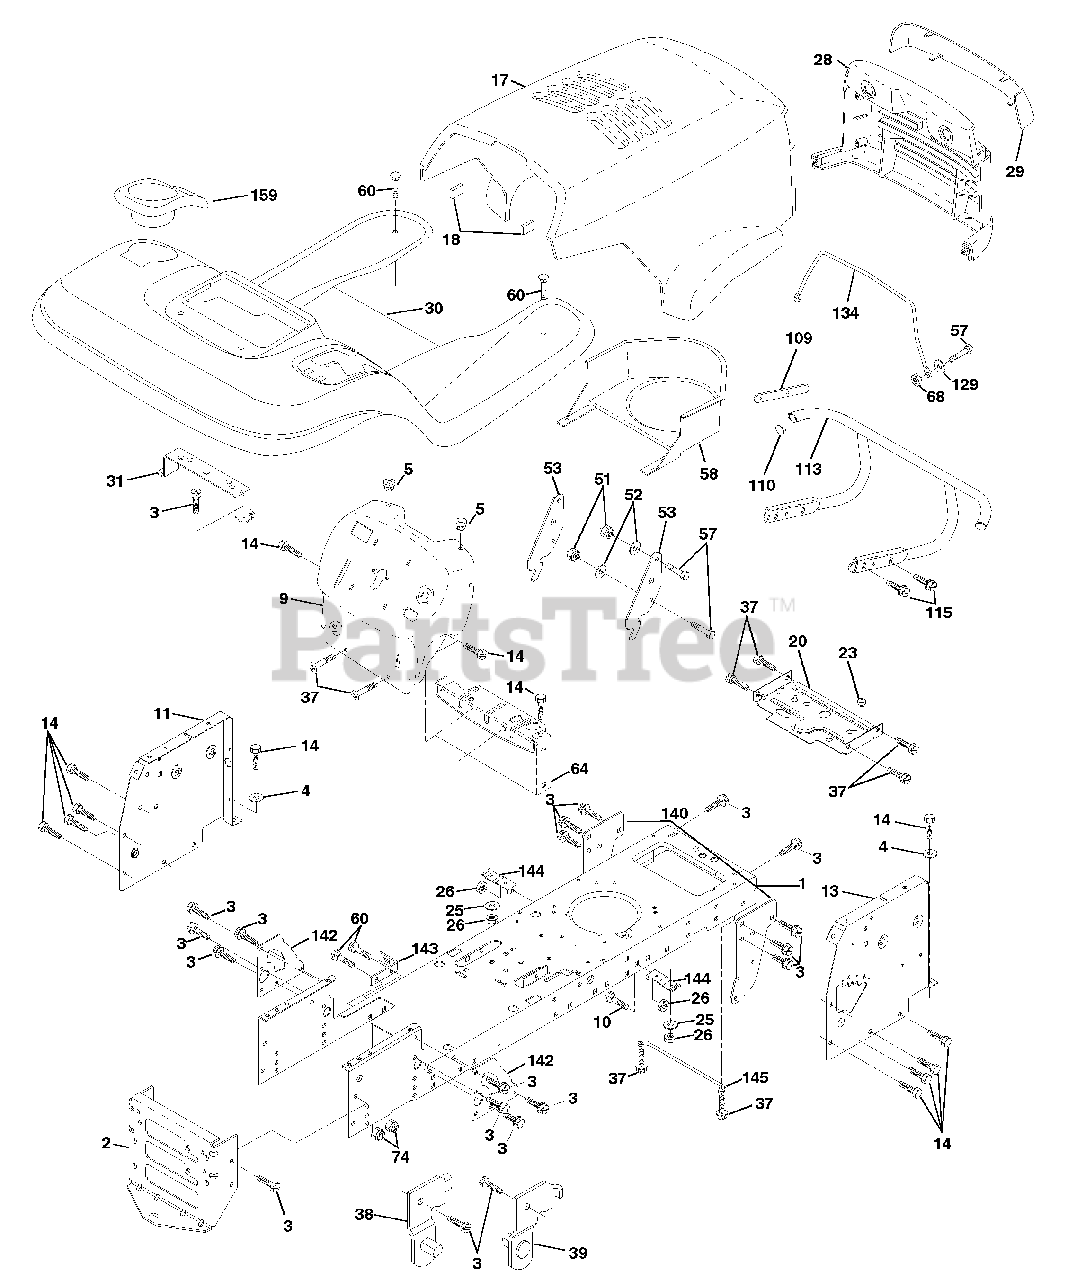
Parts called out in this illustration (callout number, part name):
1	Chassis Weldment
2	Drawbar, Stretch
3	Screw Thdrol 3/8-16x3/4 Ty-tt
4	Washer 13/32 x 3/4 x 16 Ga.
5	Bumper Hood/Dash
9	Dash Slkscr.Plm.E.A.Hm.Nc.Sym
10	Bolt Carriage 3/8-16 x 1
11	Panel Dash Lh
13	Panel Dash Rh
14	Screw Thdrol 3/8-16x1/2 Ty-tt
17	Hood LT/PL Husqvarna
18	Bumper Hood
20	Plate Mtg Battery Fuel Tank Fr
25	Washer 13/32 X 13/16 X 12 Ga
26	Nut Lock Hex W/Ins 3/8-16 Unc
28	Grille LT/PL Husqvarna
29	Lens LT/PL Husqvarna
30	Fender Footrest STLT Pnt
31	Bracket Support Fender
37	Screw Thdrol 6/16-18 x 1/2 TYT
38	Bracket, Asm. Pivot, L.H., Mower Rear
39	Bracket, Asm. Pivot, R.H., Mower Rear
51	Nut Lock Hex W/Ins 1/4-20
52	Washer 9/32 x 7/8 x 16 Ga.
53	Bracket Pnt. Pick off LT/PL Husqvarna
57	Bolt Hex 1/4-20 x 3/4
58	Air Duct Engine P/L
60	Bolt Rdhd Sqnk 3/8-16unc x 3/4
64	Dash Lower STLT
68	Nut Keps Hex 1/4-20unc
74	Nut Crownlock 3/8-16 UNC
109	Bracket Extension Bumper
110	Plug Plastic
113	Bumper Asm.
115	Screw Thdrol 3/8-16 x 1-1/4
129	Washer 9/32 x 5/8 x 16 Ga.
134	Rod Support Hood LT/PL Husq.
140	Bracket Suspension Front
142	Plate Reinforcement STLT
143	Bracket Swaybar Chassis
144	Bracket Pnt Footrest STLT
145	Rod Pivot Chassis/Hood
159	Cupholder Stlt Grey
